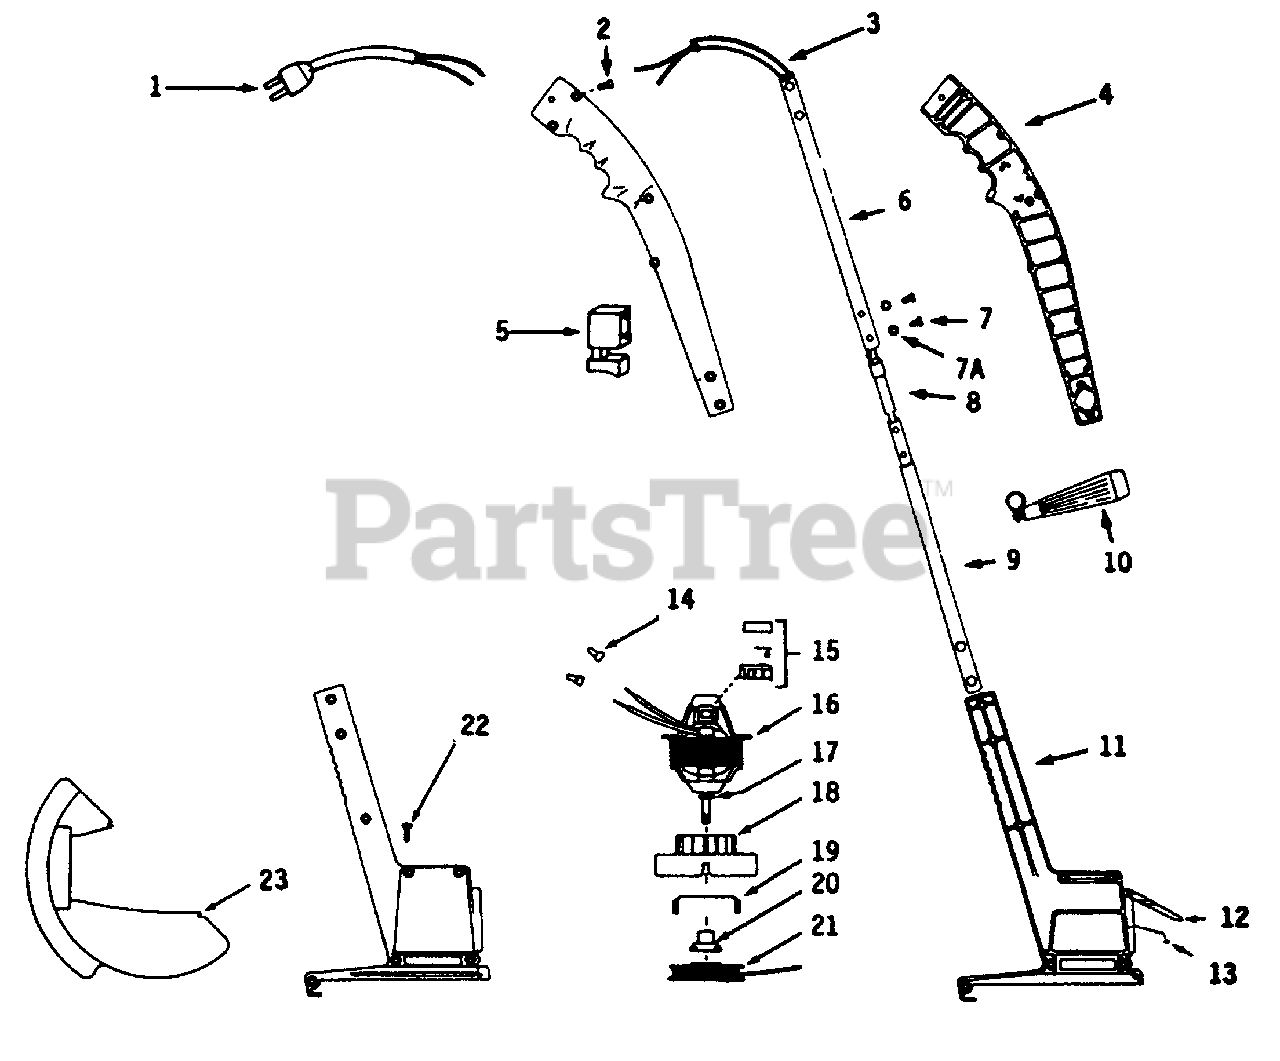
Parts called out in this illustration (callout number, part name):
1	POWER CORD PIGTAIL
4	HANDLE SET
6	TUBE, UPPER (obsolete)
7A	WASHER, LOCK
8	SCREW BARRIER
9	TUBE, LOWER (obsolete)
10	ASSIST HANDLE
11	MOTOR HOUSING SET
12	CLIP OFF LEVER
13	CLIP OFF BLADE
14	CONNECTOR
15	BRUSH KIT
16	MOTOR ASSEMBLY
17	WASHER, THRUST
19	LINE SAVER
20	HUB RETAINER
21	SPOOL WOUND
23	GUARD (obsolete)
